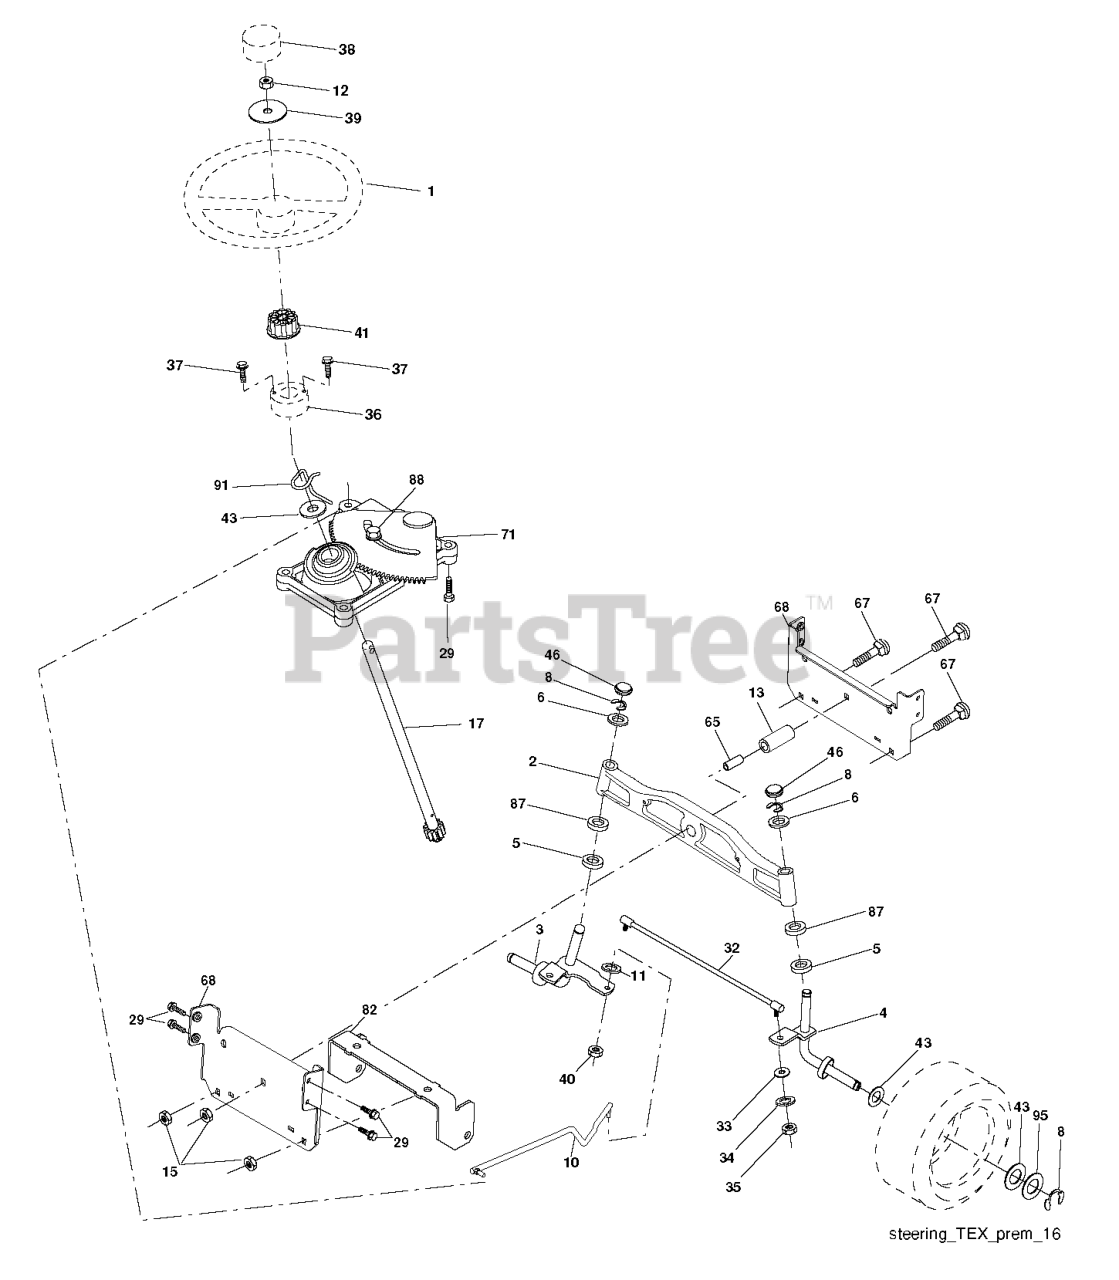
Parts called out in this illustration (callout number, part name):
1	STEERING WHEEL
2	AXLE ASSY FRONT
3	SPINDLE.ASM.LH.15"TIRES
4	SPINDLE.ASM.RH.15"TIRES
5	THRUST WASHER
10	DRAGLINK.15".TIRES.2001
11	WASHER, LOCK 3/8
12	NUT.HEX.1/2-20
13	TUBE, PIVOT AXLE
15	NUT
17	SHAFT ASM STRG
29	SCREW, 3/8-16X3/4
33	WASHER M
34	WASHER.LOCK.HVY.HLCL.SPR.5/16
35	NUT, CROWNLOCK
36	BUSHING, STRG. BLK
37	SCREW.TT.#10-32X.5.3/8.FLANGE
38	INSERT.CAP.STRG.WH.GRAY
39	WASHER 9/16"ID, 2 3/8"OD
40	NUT CROWNLOCK 3/8-24
41	ADAPTER, WHEEL STNG..
46	CAP.SPINDLE.BLACK
65	SPACER BRACE AXLE
67	BOLT CARRIAGE
68	BRACE.AXLE.15"TIRES
71	STEERING ASM
82	BRACKET.SUSP.CHASSIS.FRONT.15
87	WASHER, FLAT .781 X 1 1/2"
88	BOLT, SHOULDER 7/16-20
91	CLIP.STEERING
95	WASHER.HARDENED
